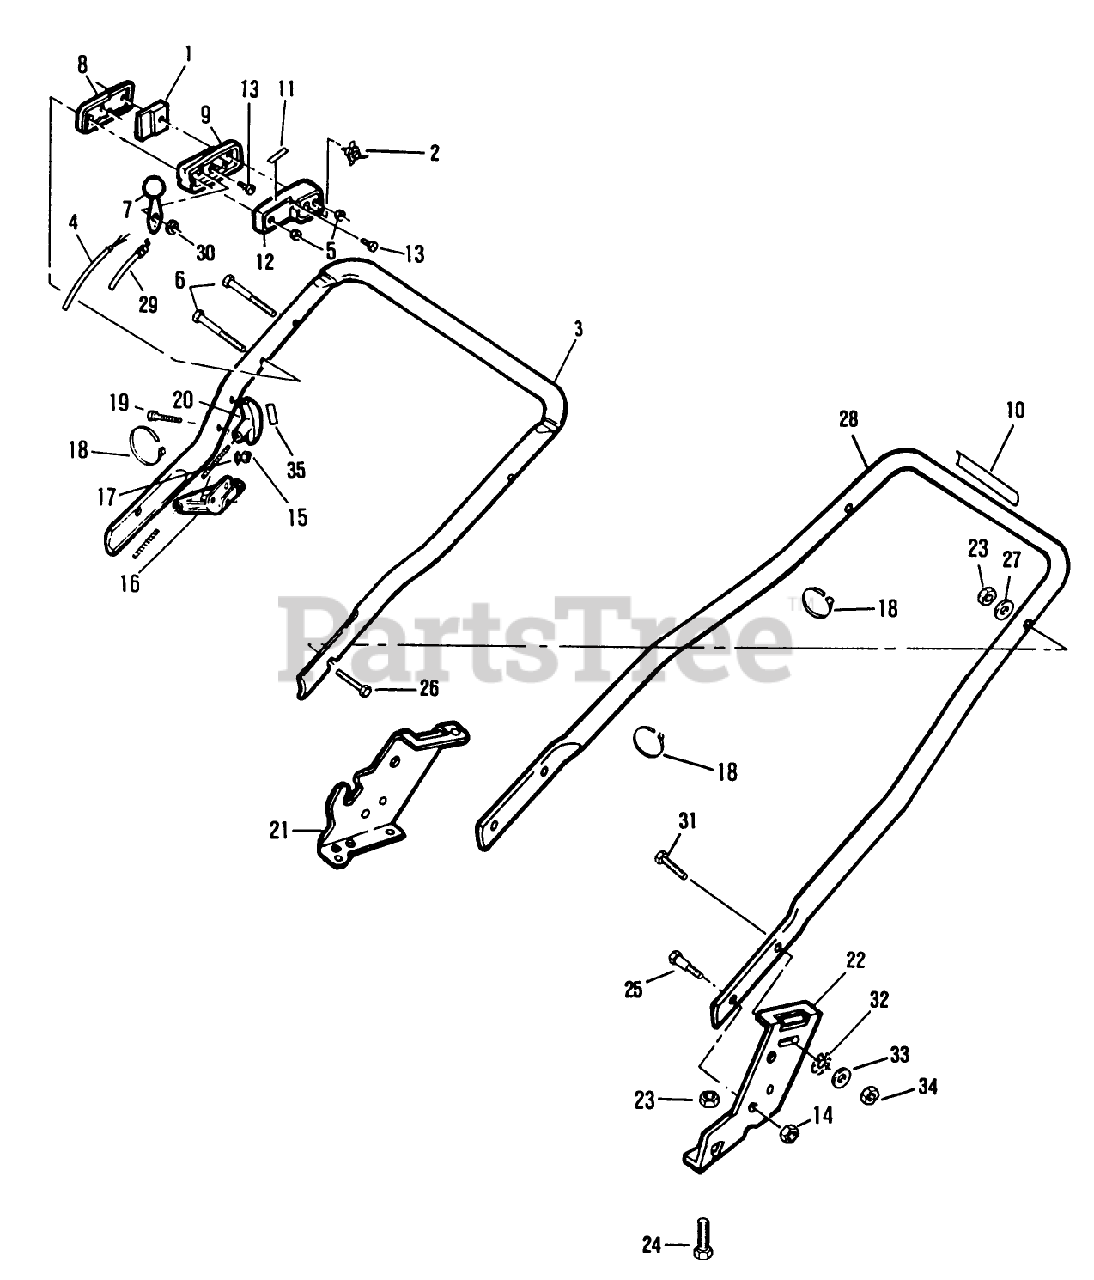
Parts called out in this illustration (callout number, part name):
5	NUT C/LOCK E
6	SCREW
7	LEVER&KNOB AY WES
8	OUTER CONTROL CASE
13	SCREW
14	NUT-JAM, LOCKING
15	LOCKNUT E
17	WASHER
20	NUT-JAM, LOCKING
23	NUT-LOCK F
25	BOLT
27	WASHER-CURVED
29	CABLE THROT WES
30	WASHER-SPRING
32	LOCK WASHER LARSON
33	WASHER
